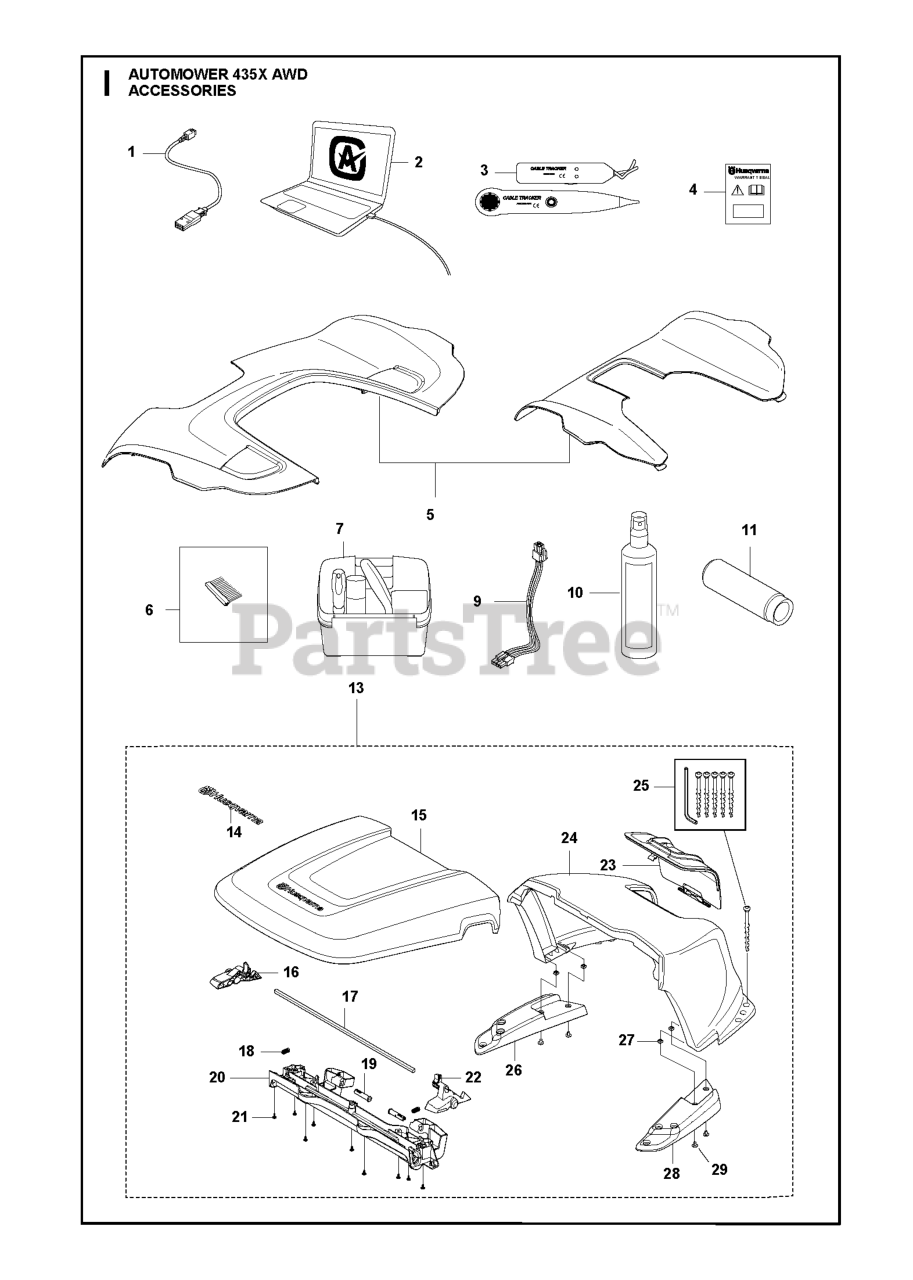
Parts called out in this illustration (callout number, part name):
1	CABLE ASSY QUICK CHARGER
3	TEST EQUIPMENT
4	LABEL WARRANTY SEAL DEALER
6	BRUSH WITH CARTON
7	CLEANING AND MAITENANCE KIT AM
9	WIRING ASSY BATTERY CABLE
10	AUTOMOWER ACCY
11	FLYWHEEL KNOCKER-FINE THREAD
14	DECAL
16	HANDLE RELEASE LEFT
17	ROD
18	SPRING SPRING CAP
19	HINGE PIN
20	BEAM
21	SCREW 14MM
22	HANDLE RELEASE RIGHT
23	HATCH
25	Screws
26	SUPPORT BASE LEFT
27	NUT
28	SUPPORT BASE RIGHT
29	SCREW IHPANM M6X25 4.6 ZP-BC
